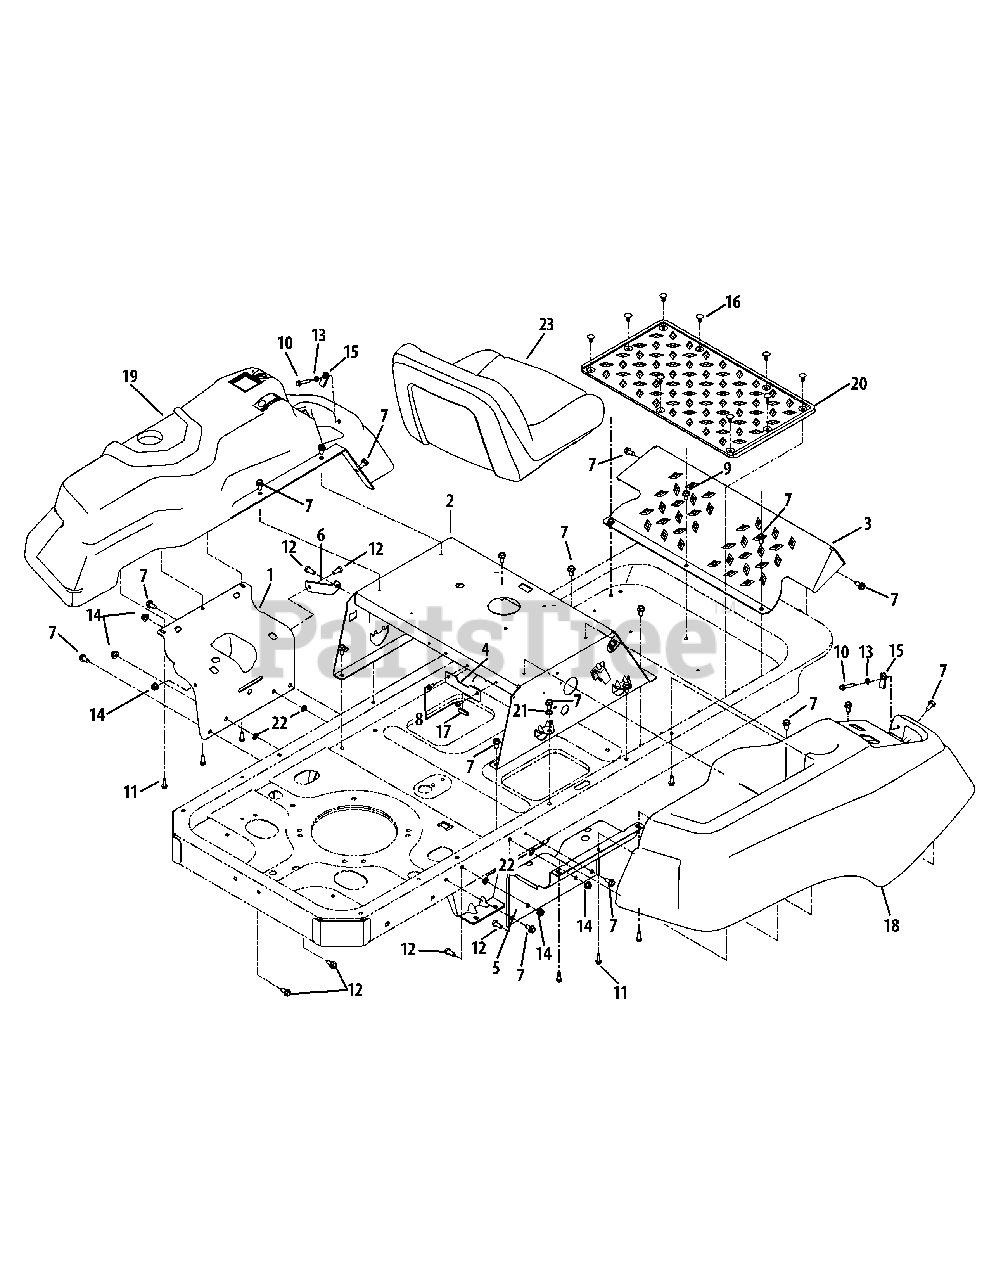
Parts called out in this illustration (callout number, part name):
1	Console Bracket Assembly - Black
1	Console Bracket Assembly - Red
2	Seat Frame Assembly - Black
2	Seat Frame Assembly - Red
3	Foot Rest Bracket - Black
3	Foot Rest Bracket - Red
4	Battery Hold-Down Bracket
5	Console Mount Bracket - Black
5	Console Mount Bracket - Rede
6	Fuel Tank Support Bracket
7	Hex Washer Screw, 5/16-18 x .750
8	Hex Washer Screw, 1/4-20 x .500
9	Hex Washer Screw, 5/16-18 x .625
10	Hex Washer Screw, 1/4-20 x 1.500
11	Hex Washer Screw, 1/4-15 x .750
12	Screw, 1/4-15 X .50
13	Jam Nut, 1/4-20
14	Flange Lock Nut, 5/16-18
15	Speed Nut, 1/4-20
16	Ratchet Clip
17	Trim Strip
18	RH Console (Black)
18	RH Console (Oyster Gray)
19	LH Console (Black)
19	LH Console (Oyster Gray)
20	Foot Pad
21	Lock Washer, 3/8
22	Speed Nut, .3125
23	High Back Seat
